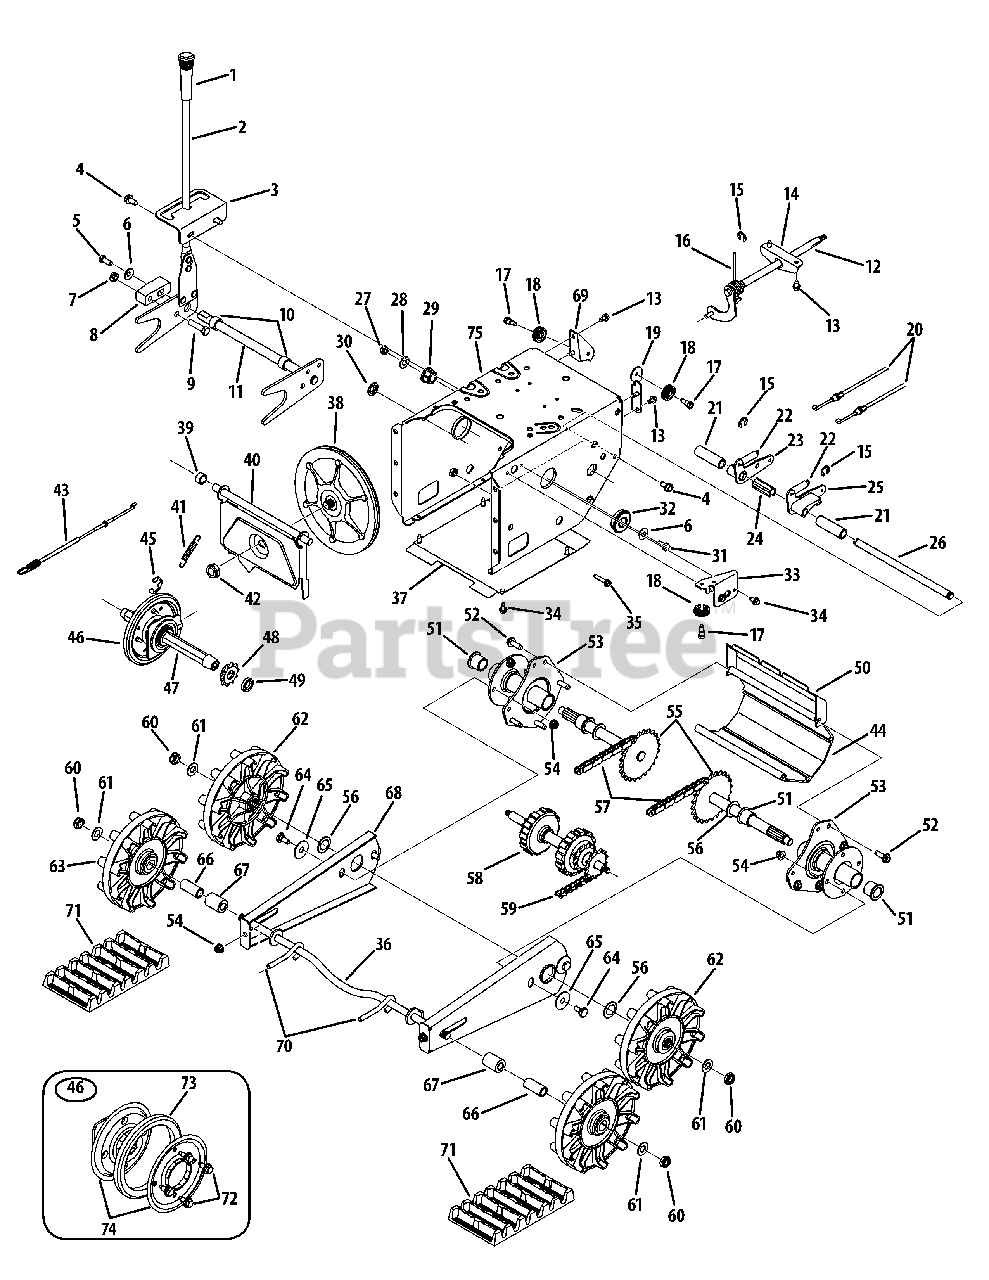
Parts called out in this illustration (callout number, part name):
1	Grip, .5 ID x 3.45
2	Track Lock Handle Assembly
3	Lockout Track Bracket Plate
4	Hex Washer Screw, 5/16-18 x .750
5	Hex Screw, 5/16-24 x .75
6	Bell Washer, .340 x .872 x .060
7	Hex Lock Nut, 3/8-16
8	Lift Shaft Drive
9	Hex Screw, 3/8-16 x 1.50
10	Spacer, .828 ID x .875 OD x .500
11	Pivot Rod Assembly
12	Shift Rod Assembly
13	Hex Washer Screw, 1/4-20 x .500
14	Shift Frame Bracket
16	Torsion Spring, .750 ID x .968
17	Shoulder Screw, .34 x .335 x 1/4-28
18	Cable Roller
19	Auger Cable Guide Bracket
20	Track Steering Cable
21	Spacer, .515 x 735 x 2.44
22	Extension Spring, .48 OD x 2.03
23	Dogg Assembly, RH
24	Spacer, .491 ID x 1.87
25	Dogg Assembly, LH
26	Shift Actuator
27	Jam Lock Nut, 3/8-24
28	Flat Washer, .406 x .875 x .059
29	Hex Flange Bearing
30	Speed Nut, .500
31	Hex Lock Screw, 5/16-18 x .625
32	Ball Bearing
33	Auger Cable Support Guide
34	Hex Washer Screw, 1/4-20 x .625
35	Hex Washer Screw, 1/4-20 x 1.000
36	Axle Assembly
37	Track Frame Cover
38	Friction Wheel Disc Assembly
39	Spacer, .525 ID x .750 x .42
40	Friction Wheel Support Bracket
41	Extension Spring
42	Flange Nut, 5/16-18
43	Drive Clutch Cable
46	Friction Wheel Assembly
47	Hex Track Shaft
48	Sprocket, 10T
49	Spacer, .675 ID x 1.00 OD x .23
52	Hex Washer Screw, 5/16-18 x 1.0
53	Track Hub Assembly
54	Flange Lock Nut, 5/16-18
55	Track Axle Assembly
56	Flat Washer, .793 x 1.24 x .06
58	Drive Track Shift Assembly
60	Jam Lock Nut, 1/2-20
61	Flat Washer, .510 x 1.00 x .060
62	Track Drive Wheel
63	Track Idler Wheel
64	Shoulder Screw, .43 x .56 5/16-18
65	Flat Washer, .442 x 1.38 x .060
66	Spacer, .51 ID x .75 OD x 1.67
67	Spacer, .510 ID x 1.0 OD x 1.34
69	Drive Cable Guide Bracket
70	Eye Bolt, 5/16-18 x 3.0
71	Snow Trac
72	Hex Washer Screw, 1/4-14 x .625
73	Friction Wheel
74	Friction Plate
75	Frame Assembly
